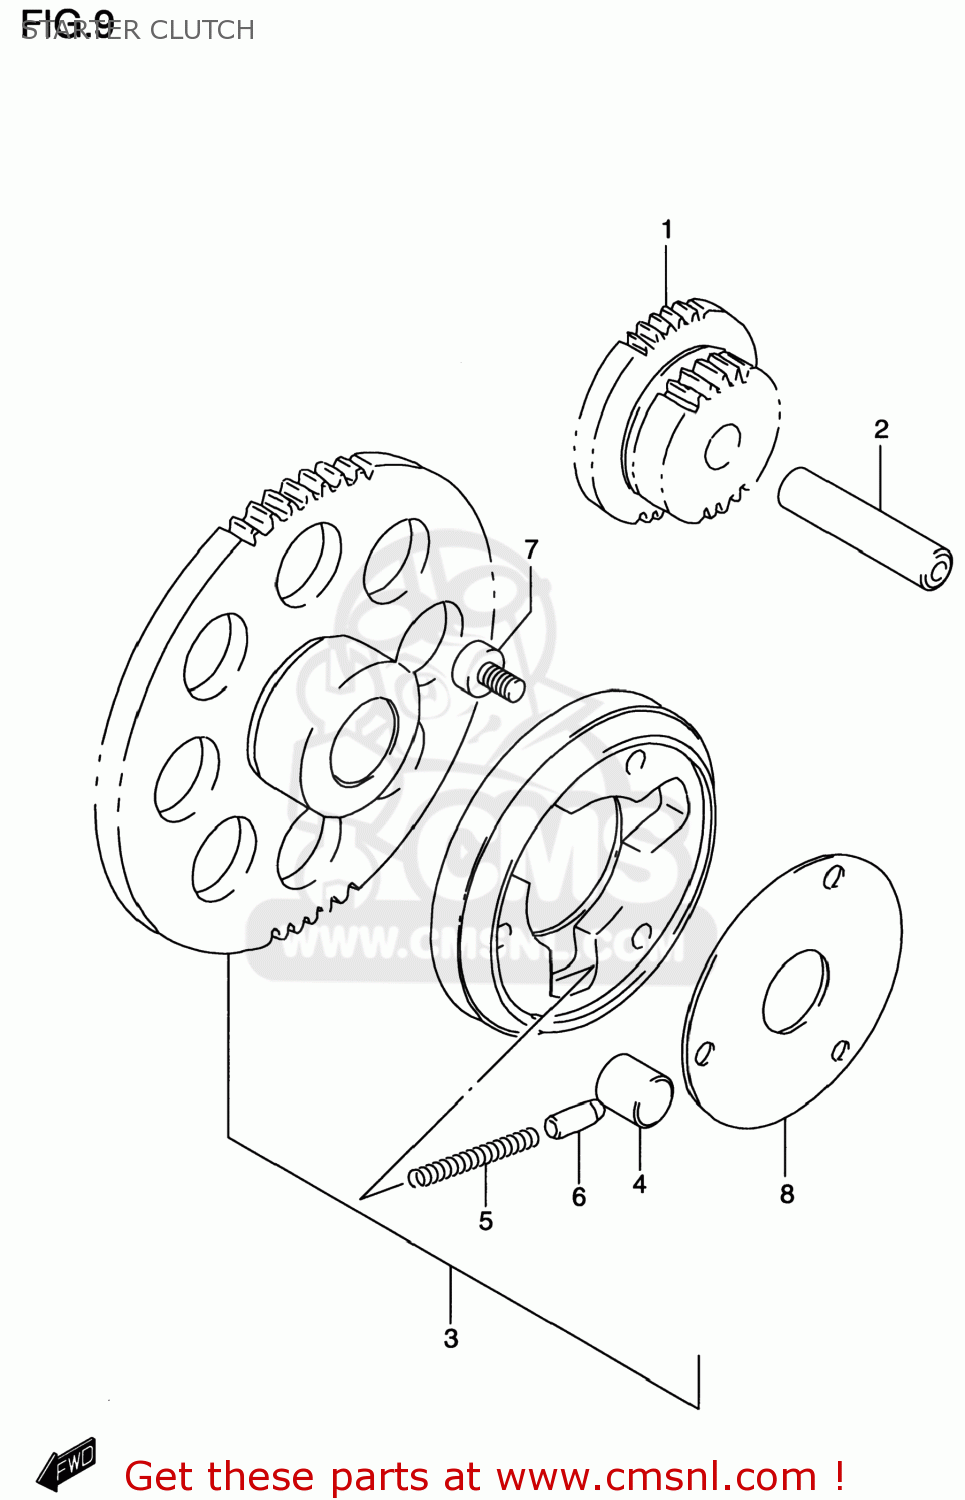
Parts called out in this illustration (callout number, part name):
1	GEAR,STARTER IDLE
2	PIN(7.4X13X56)
3	CLUTCH SET,STARTER
4	ROLLER(15X13)
5	SPRING
6	PIECE,PUSH
7	BOLT
8	SHIM,STARTER CLUTCH HUB
